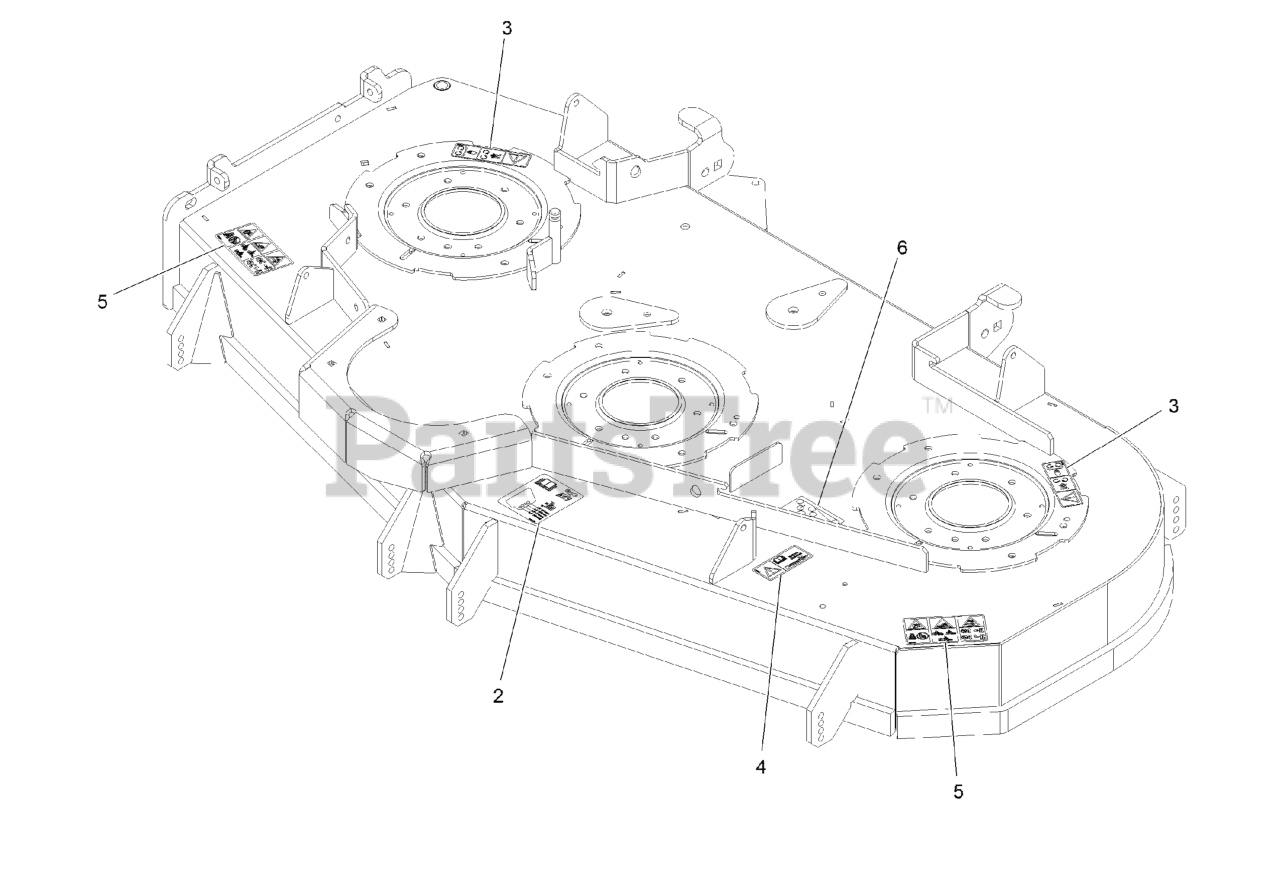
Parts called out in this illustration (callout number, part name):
2	DECAL-ROLLER, ANTI-SCALP
3	DECAL-COVER, MISSING
4	DECAL-TORQUE, BOLT
5	DECAL-DANGER THROWN OBJECTS
6	DECAL-BELT 60 SIDE
